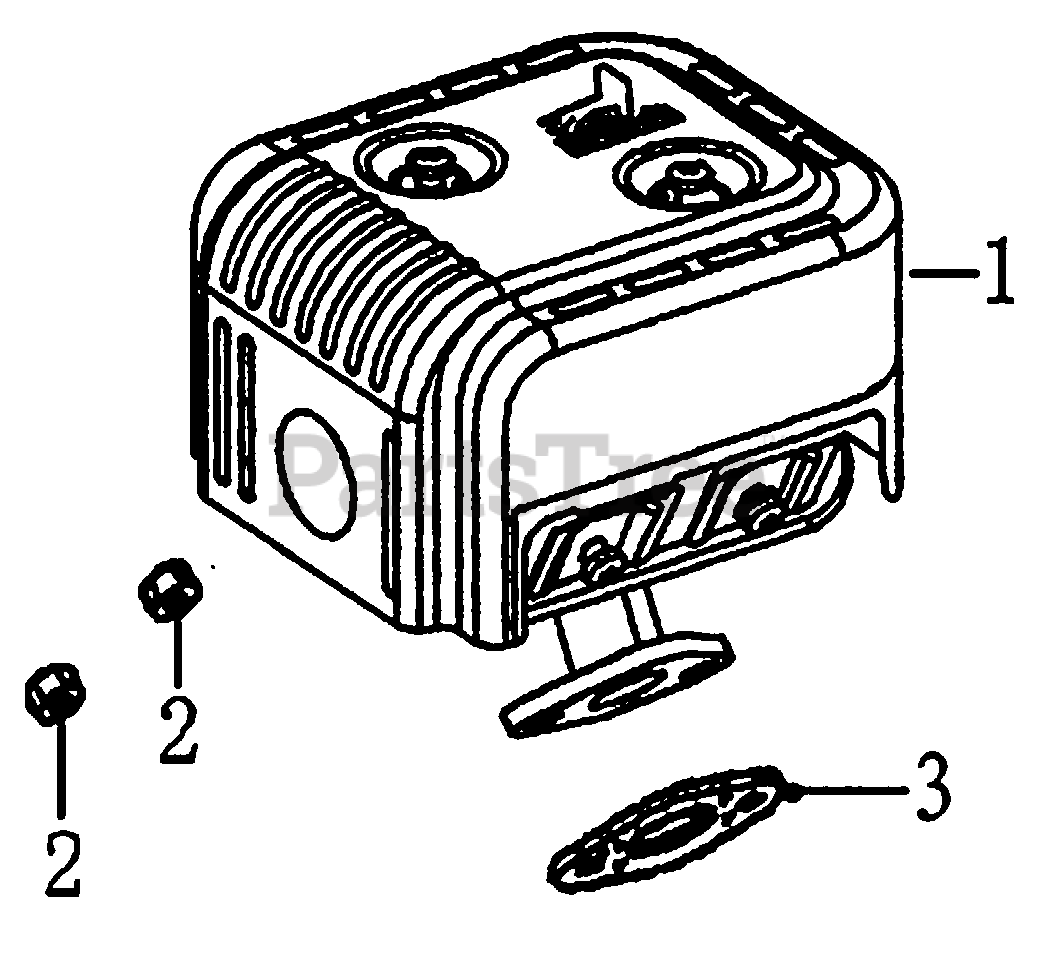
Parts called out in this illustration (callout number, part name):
1	MUFFLER ASSY.
2	NUT, HEX.
3	GASKET, MUFFLER
